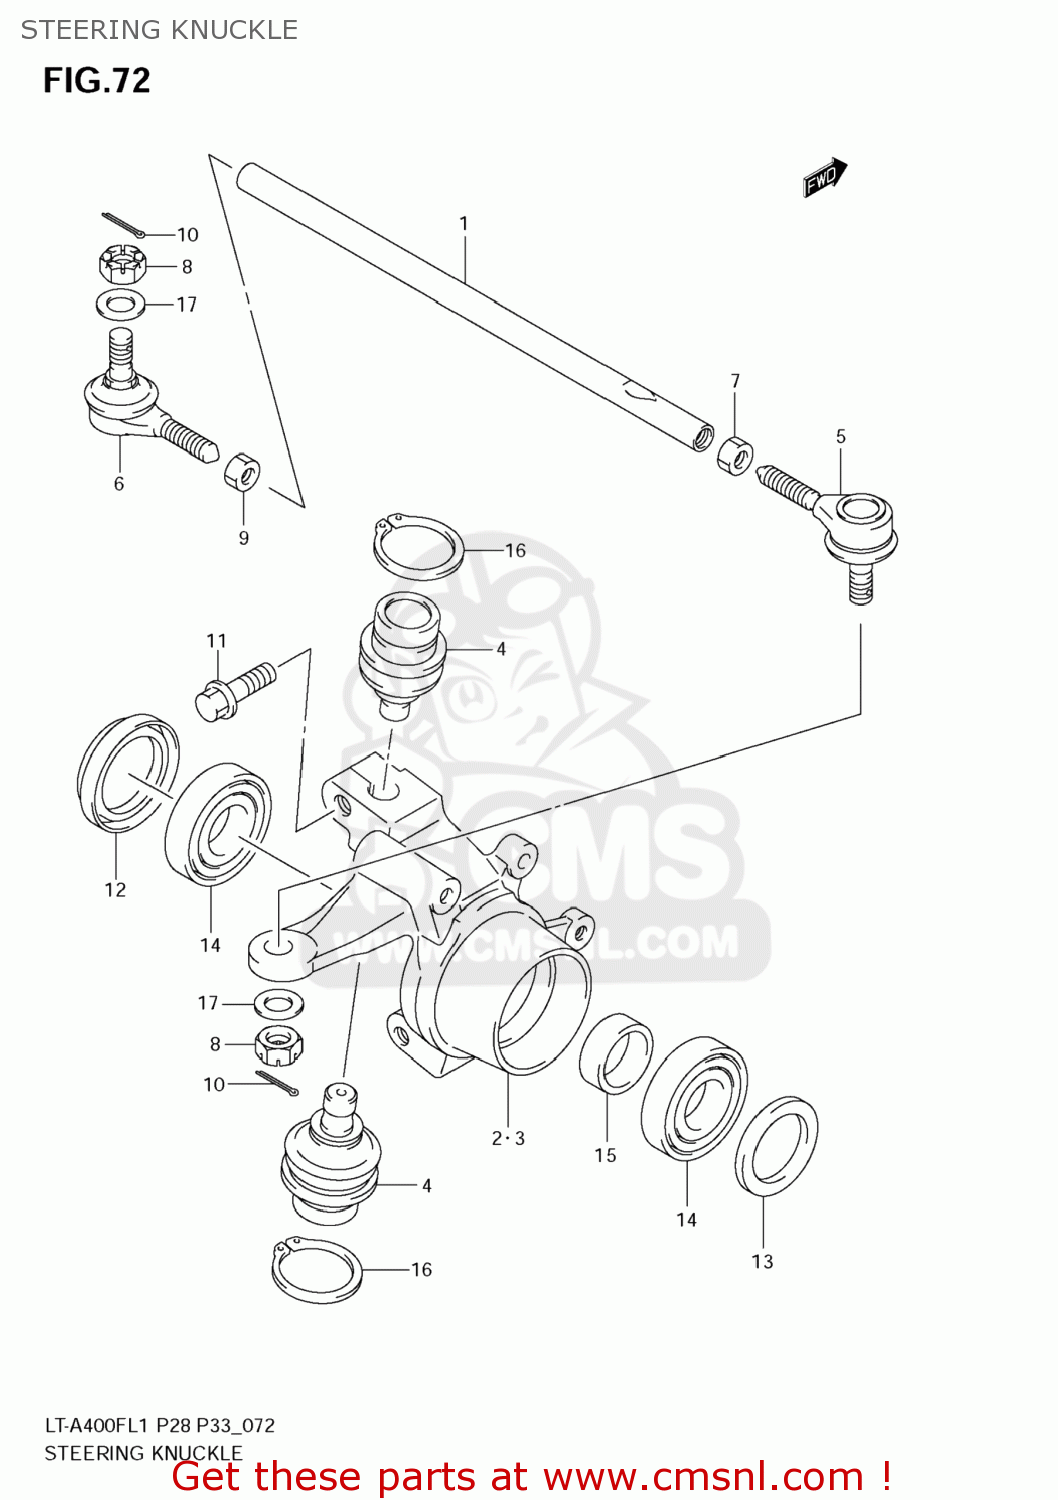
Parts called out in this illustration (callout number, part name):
1	TIE ROD,STEERING
2	KNUCKLE,STEERING,R
3	KNUCKLE,STEERING,L
4	END,KNUCKLE STEERING
5	END,ROD,R
6	END,ROD,L
7	NUT,TIE ROD,R
8	NUT
9	NUT
10	PIN
11	BOLT,KNUCKLE(10X30)
12	SEAL,OIL(38X55X8)
13	SEAL,OIL(38X55X9)
14	BEARING
15	SPACER,HUB BEARING
16	CIRCLIP
17	WASHER(10.5X19X2)
